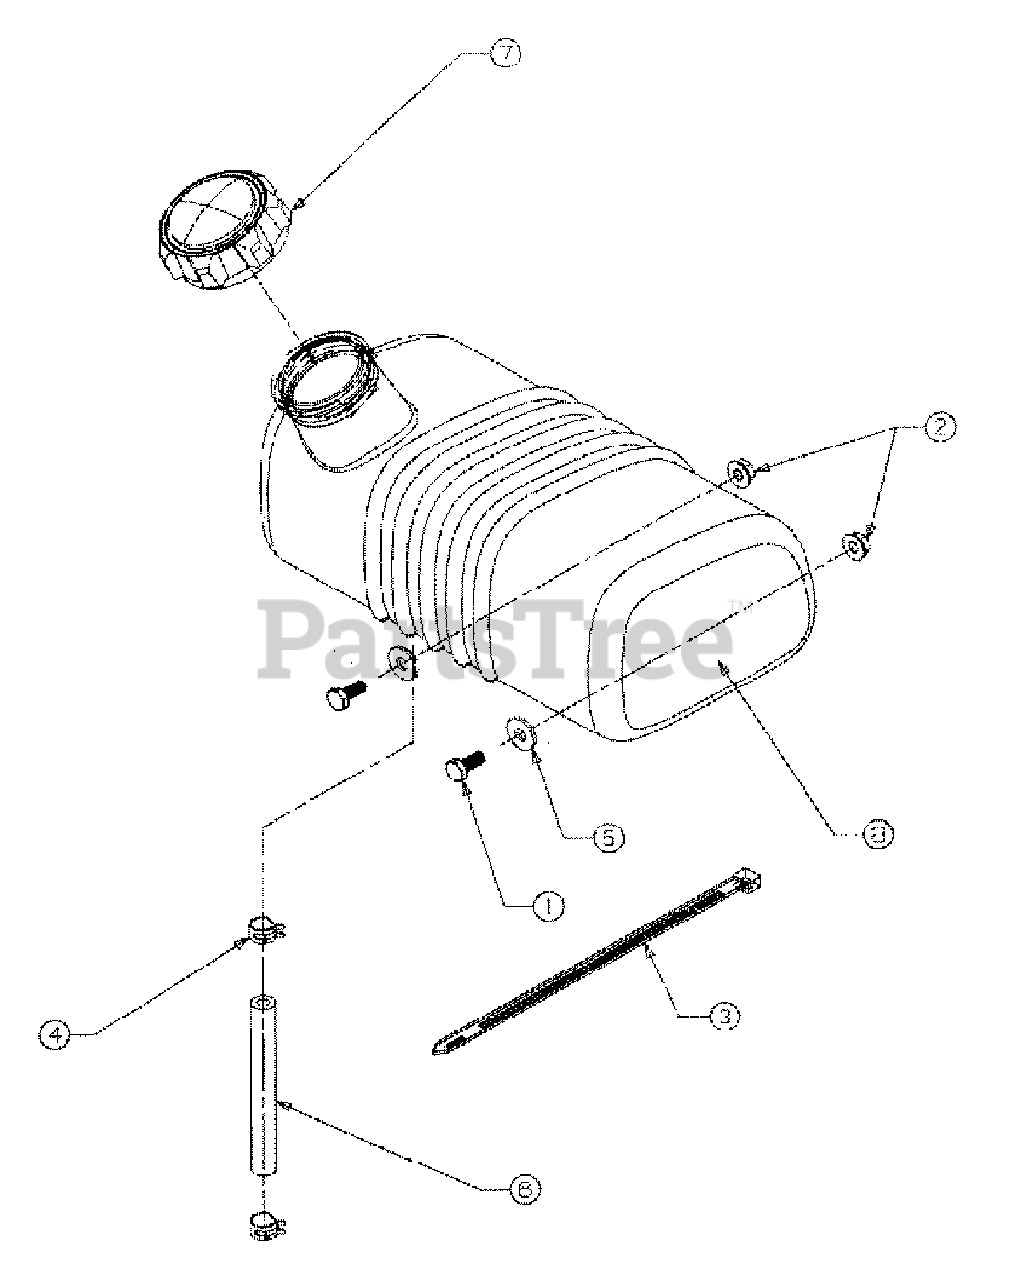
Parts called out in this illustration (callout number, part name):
1	SCREW-HEX
2	NUT-HEX LOCK FLANGE
3	CABLE TIE
4	CLAMP-HOSE
5	WASHER-FLAT
6	HOSE-FUEL LINE 12"
7	CAP-FUEL
8	TANK-FUEL 1 GALLON
